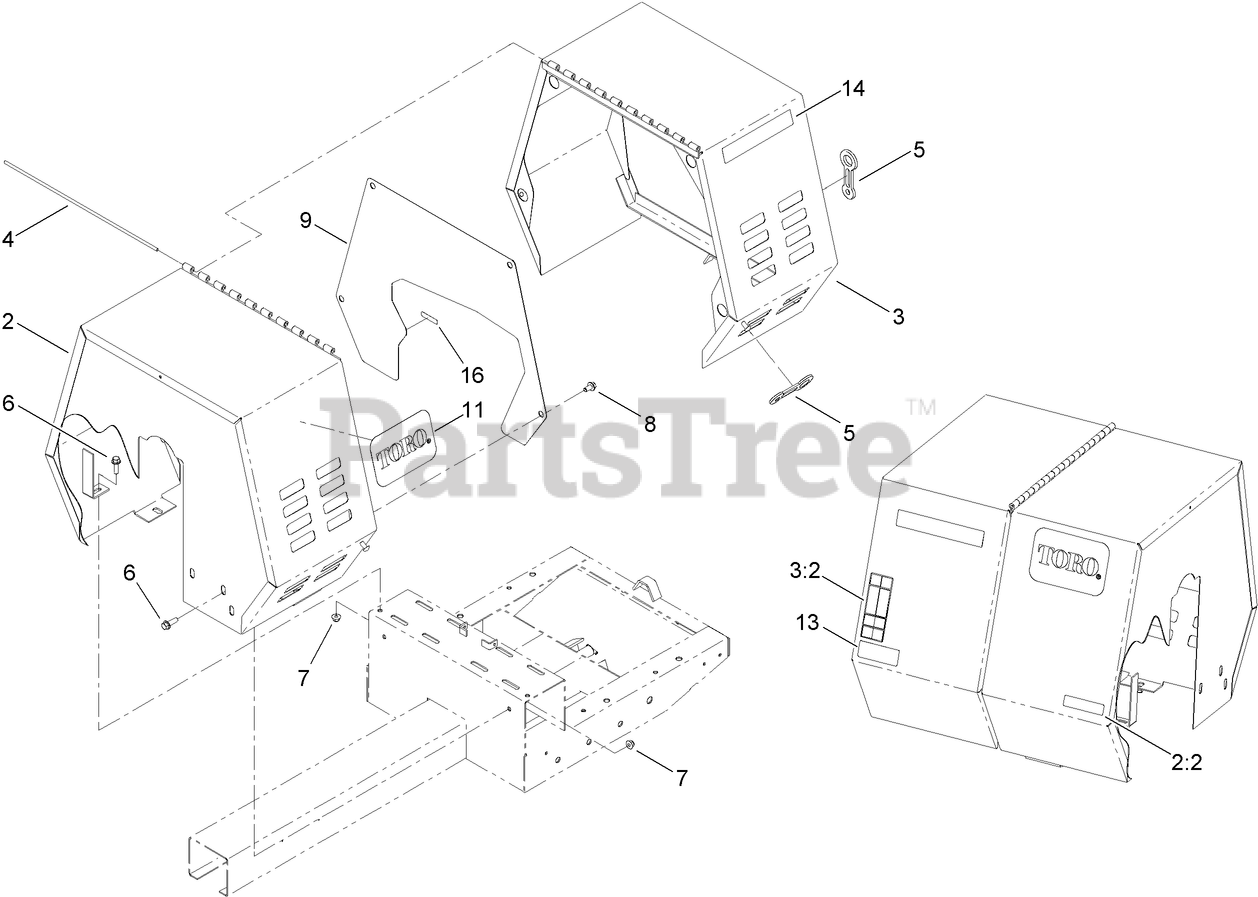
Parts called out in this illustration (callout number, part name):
2	STATIONARY COWL ASM
2:2	DECAL-ARRESTER, SPARK
3	MOVABLE COWL ASM
3:2	DECAL-WARNING
5	LATCH-RUBBER
6	SCREW-HHF
7	NUT-HF, NI
8	SCREW-HWH
9	PLATE-GUARD, BELT
11	DECAL
14	DECAL-MM-850E
16	DECAL-GREASE
